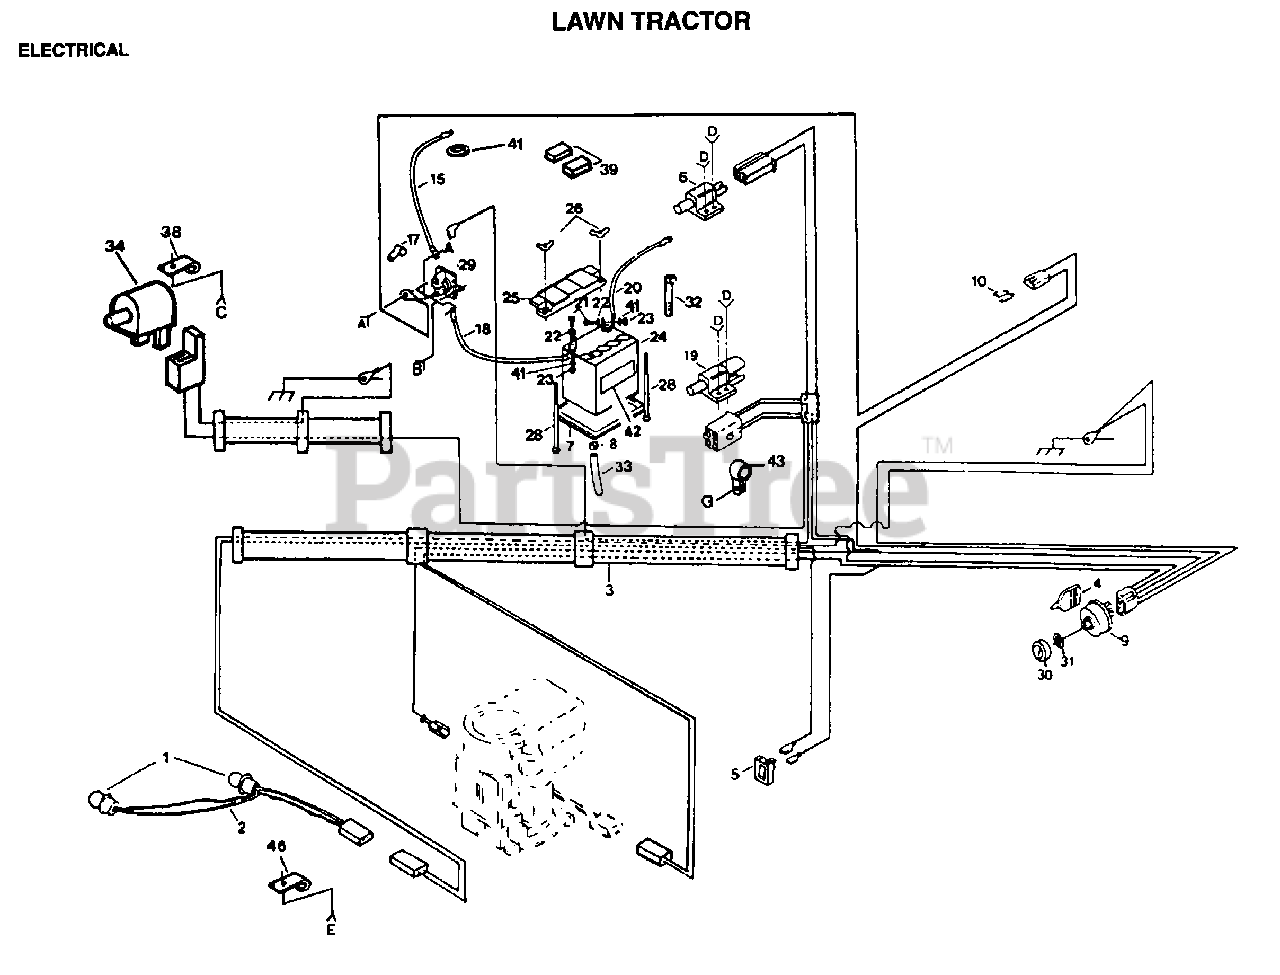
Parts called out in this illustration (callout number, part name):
2	HARNESS T
3	"HARNESS,WIRING"
5	SWITCH LT
6	SWITCH-INTER. GT
7	"TRAY T, BATTERY"
8	HOSE CLAMP T
10	FUSE HYT
12	NUT
13	BOLT
14	NUT
17	COVER, TERMINAL
18	STARTER CABLE GT
19	SWITCH INTERLOCKT
21	BOLT LT
22	WASHER
28	BOLT
32	WIRE TIE
34	SWITCH SEAT
37	"NUT,KEPS"
39	"CAP,BATTERY "
41	LOCKWASHER
42	DECAL
43	INSUL CLIP T
44	SCREW
45	SCREW LT
46	CLIP T
